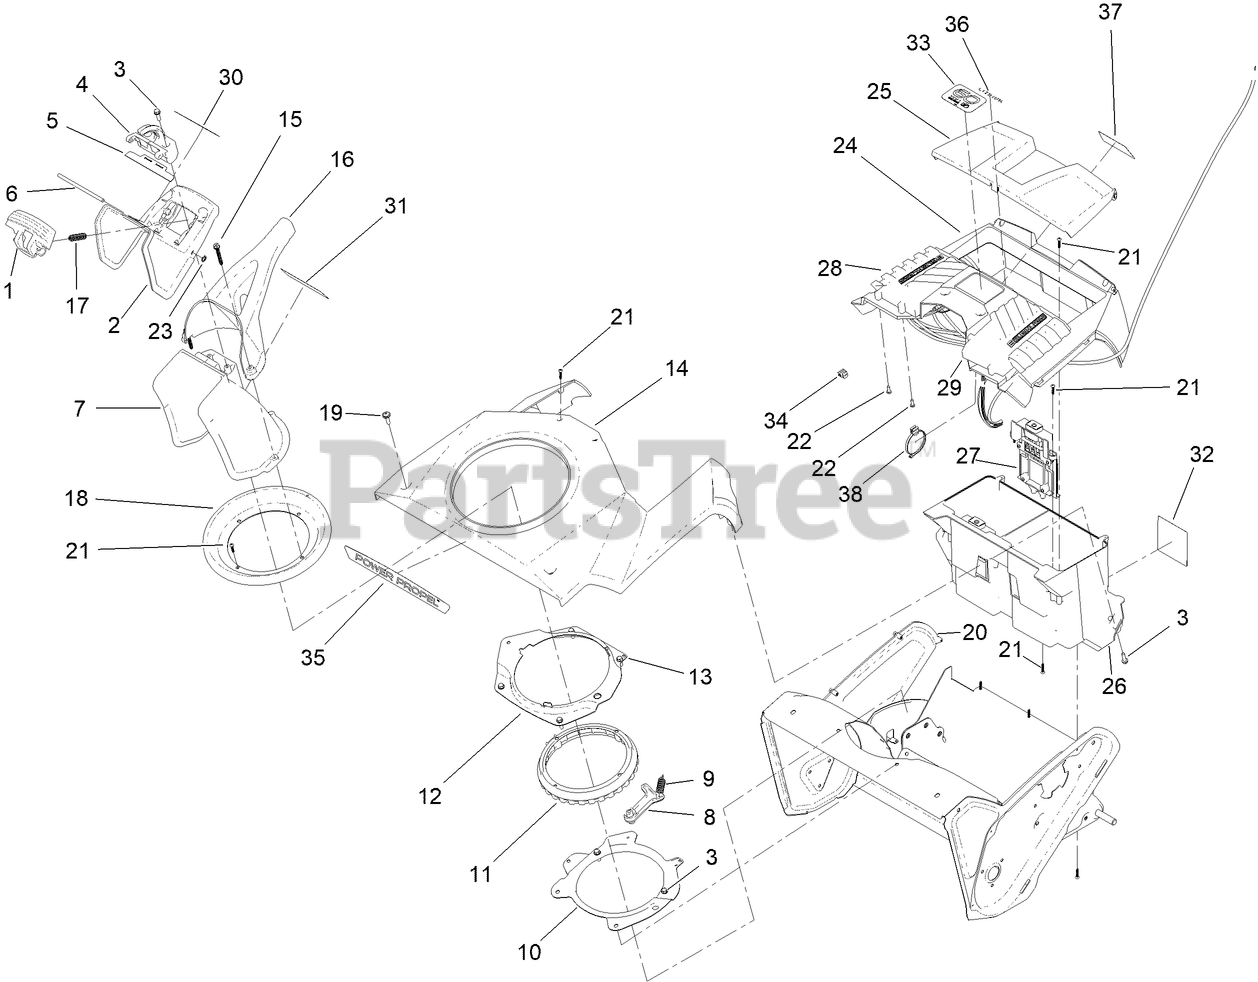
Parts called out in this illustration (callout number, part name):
1	TRIGGER-DEFLECTOR
2	DEFLECTOR-CHUTE,
3	SCREW-HWH
4	HINGE-RATCHET, DEFLECTOR
5	SEAL-DEFLECTOR
6	HINGE PIN-DEFLECTOR
8	PAWL-DETENT
9	SPRING-EXTENSION
10	RING-SUPPORT, CHUTE
11	RING-CHUTE, DETENT
12	RETAINER-RING, CHUTE
13	SCREW-HWH
14	SHROUD
15	SCREW-HWH, PLASTITE
16	HANDLE-CHUTE
17	SPRING-COMPRESSION
18	SEAL-RING, CHUTE
19	SCREW-PPH
20	COVER-SIDE
21	SCREW-PPH
22	SCREW-PPH
23	RING-RETAINING
24	COVER-HOUSING
25	COVER-BATTERY BUCKET
26	battery bucket
27	BATTERY TRACK ASM (60A)
28	PARALLEL MODULE-CONTROLLER E21SP
29	MOTOR CONTROLLER- E21SP
30	DECAL-DANGER
31	DECAL-DANGER, DISCHARGE
32	DECAL-MODEL/SERIAL
33	DECAL - 60V POWERHEAD, E21SP
34	CLIP-EDGE, PARALLEL W/TIE
35	DECAL - POWER PROPEL
36	ARTWORK-LITHIUM
37	DECAL-BATTERY BUCKET
38	CLIP-EDGE, PERPENDICULAR W/TIE
